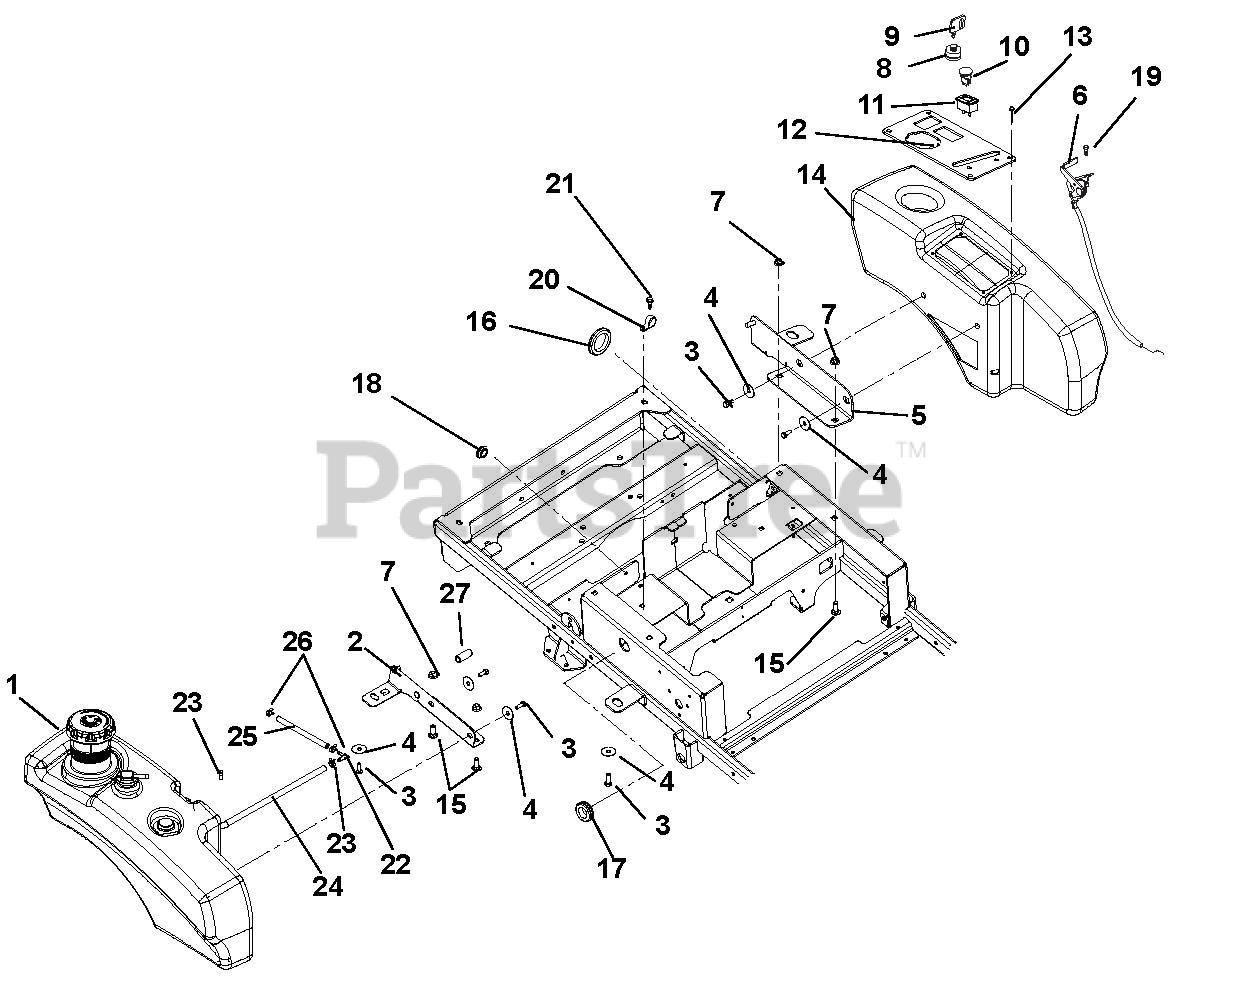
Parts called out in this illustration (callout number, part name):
1	Tank, XL Non-Permeable Fuel
2	Weldment, RH Tank Mount
3	Bolt, Serrated Hex Flange Washer Head .312-18 x .50
4	Washer, Flat Steel .347 x 1.254 x .048
5	Weldment, LH Fender Mount
6	Cable, Throttle
7	Nut, .38-16 Nyloc Flange
8	Key Switch
9	Key, w/Cap
10	Switch, Clutch
11	Hour Meter, Digital
12	Panel, Control
13	Screw, Hex .25 x 14-.75
14	Fender, XL
15	Bolt, Round Head Square Neck .38-16 x 1.00 Grade 5
16	Grommet, 2.00"
17	Grommet .125 x 1.000 ID
18	Grommet, Rubber 5/8 ID/1.13 OD
19	Screw, Tapping 10-24 x .50 Hex Washer Head Thread
20	Clamp, Cushioned Steel
21	Screw, Tap Hex Washer Head .38-16 x .5
22	Fitting, 3/16 x 1/4 90 Degree VAC
23	Clamp, Fuel Line
24	Hose, .25 Low-Perm Bulk Gas
25	Hose, .188 Low-Perm Bulk Gas
26	Clamp, Hose, Spring .188
27	Cap, End .315 x 1.00
